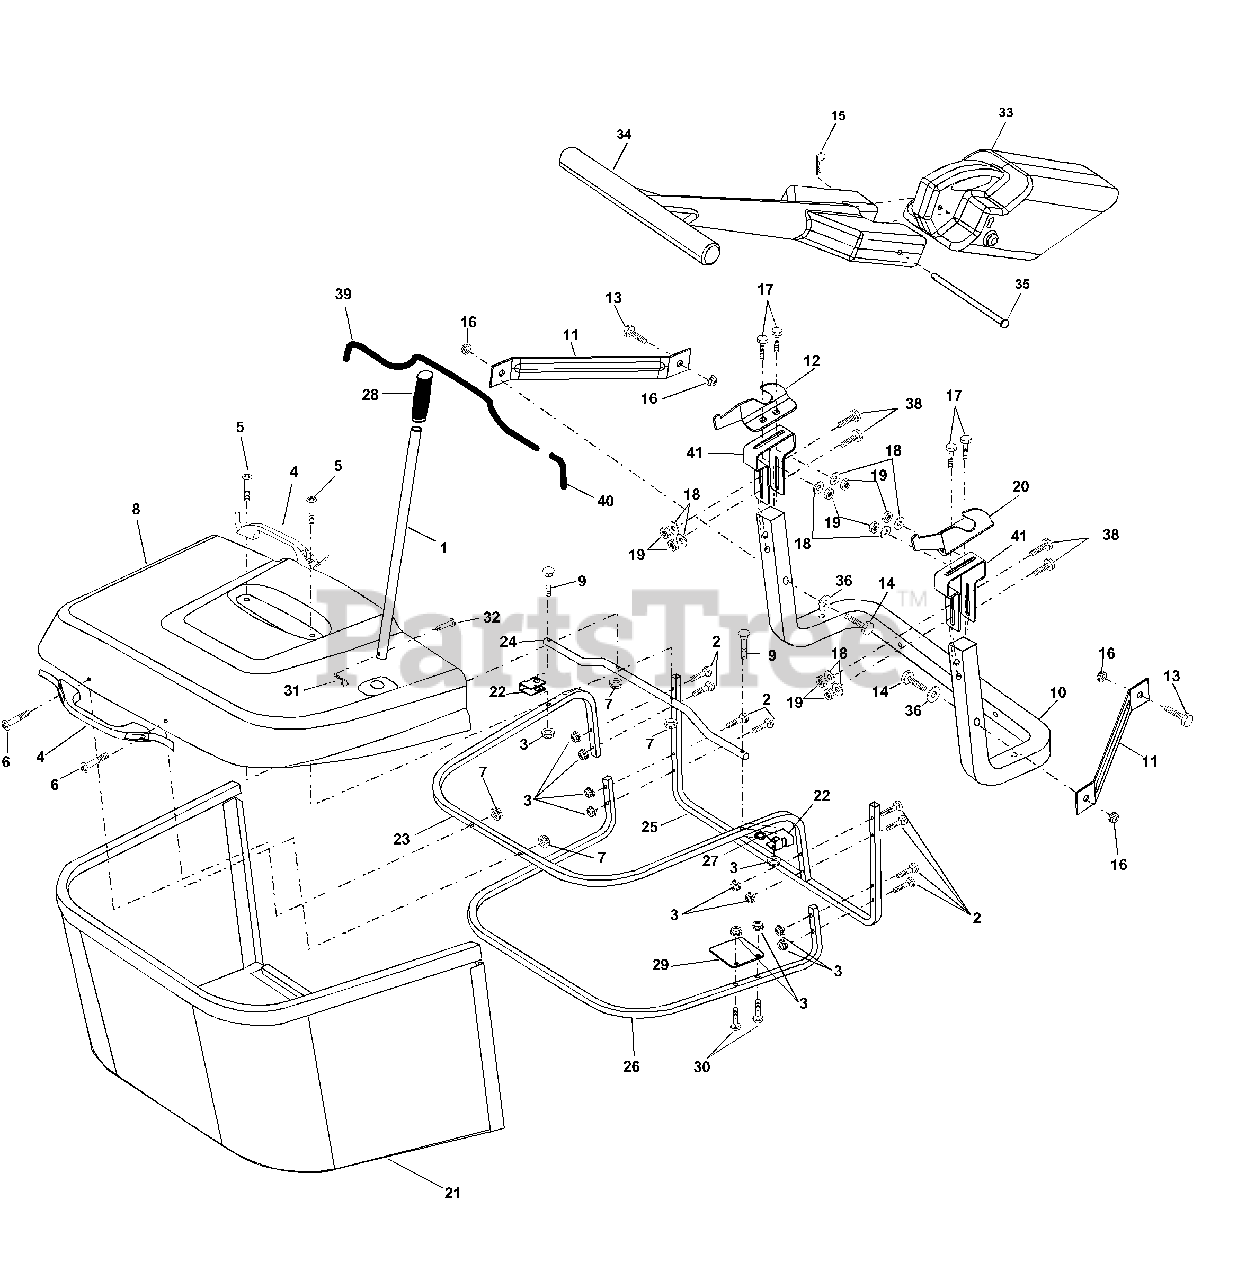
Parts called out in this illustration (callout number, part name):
1	Tube Handle Bagger CRD
2	Bolt Carriage 1/4-20 x 2.0 Gr.5
3	Nut Lock 1/4 Lge Flg Gr. 5 Zinc
4	Handle Bagger w/Lvrs Blk CRD
5	Screw Pan Head #10-24 x 1.50 Blk
6	Screw Pan Hd
7	Nut Wiz Lock Hex Serr/Hd 10-24
8	Cover Bagger Plastic CRD MS422
9	Bolt Carriage 1/4-20 x 2.25d x Gr.5
10	Tube Support Bagger CRD
11	Bracket Support Upper Bag CRD
12	Bracket Pnt Adj Bagger Lh CRD
13	Bolt Rdhd Sht Sqnk 3/8-16 x 3/4
14	Bolt Hex 3/8-16 x 2-1/2 Gr.5
15	Retainer Spring
16	Nut Lock Flg 3/8-16 Unc
17	Bolt Rdhd Sht Sqnk 5/16 -18 Unc x 3/4
18	Washer 11/32 x 3/4 x 16 Ga.
19	Nut Crownlock 5/16-18 Blk D
20	Bracket Pnt Adj Bagger Rh CRD
21	Bag Asm CRD
22	Bracket Side Bagger CRD
23	Tube Upper Bagger CRD
24	Tube Pivot Bagger CRD
25	Tube Front Bagger CRD
26	Tube Lower Bagger CRD
27	Bushing Snap Bagger CRD
28	Grip Handle Black
29	Plate Stop Bagger handle CRD
30	Bolt Carriage 1/4-20 x 1-1/4 Gr.5
31	Retainer Spring 1" Zinc/Cad
32	Rivet Rd Hd Drilled 3/8 Dia
33	Plug Mulcher
34	Handle Mulcher
35	Pin Mulcher
36	Washer 13/32 x 1-1/4 x 16 Ga.
38	Bolt 5/16-18 x 2-1/2
39	Seal, 26", long
40	Seal, 7", short
41	Bracket Pnt Adj Pvt Bagger CRD
